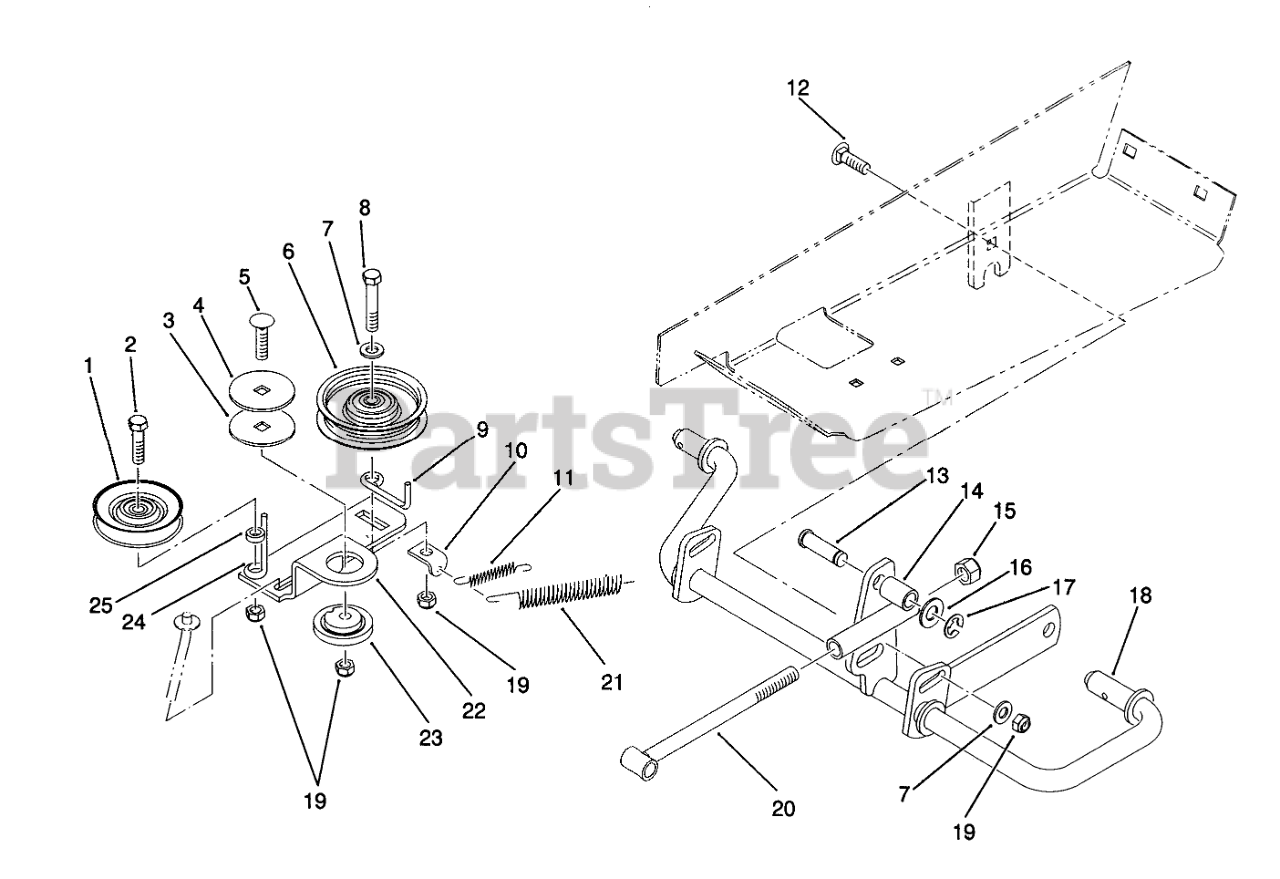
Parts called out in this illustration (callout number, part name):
1	Pulley
2	Screw-Cap, Hex. Hd.
3	WASHER-BEARING
4	WASHER
5	Bolt-Carriage
6	Idler Pulley
7	Washer
8	Screw-Cap, Hex. Hd.
9	GUIDE-BELT
10	CLIP - SPRING
11	SPRING-EXTENSION
12	Bolt-Carriage
15	Nut
16	Washer
17	E Ring
18	Shaft-W.A.
19	Nut
21	SPRING - CLUTCH
22	ARM-IDLER
23	BUSHING
24	GUIDE-BELT
25	SPACER
